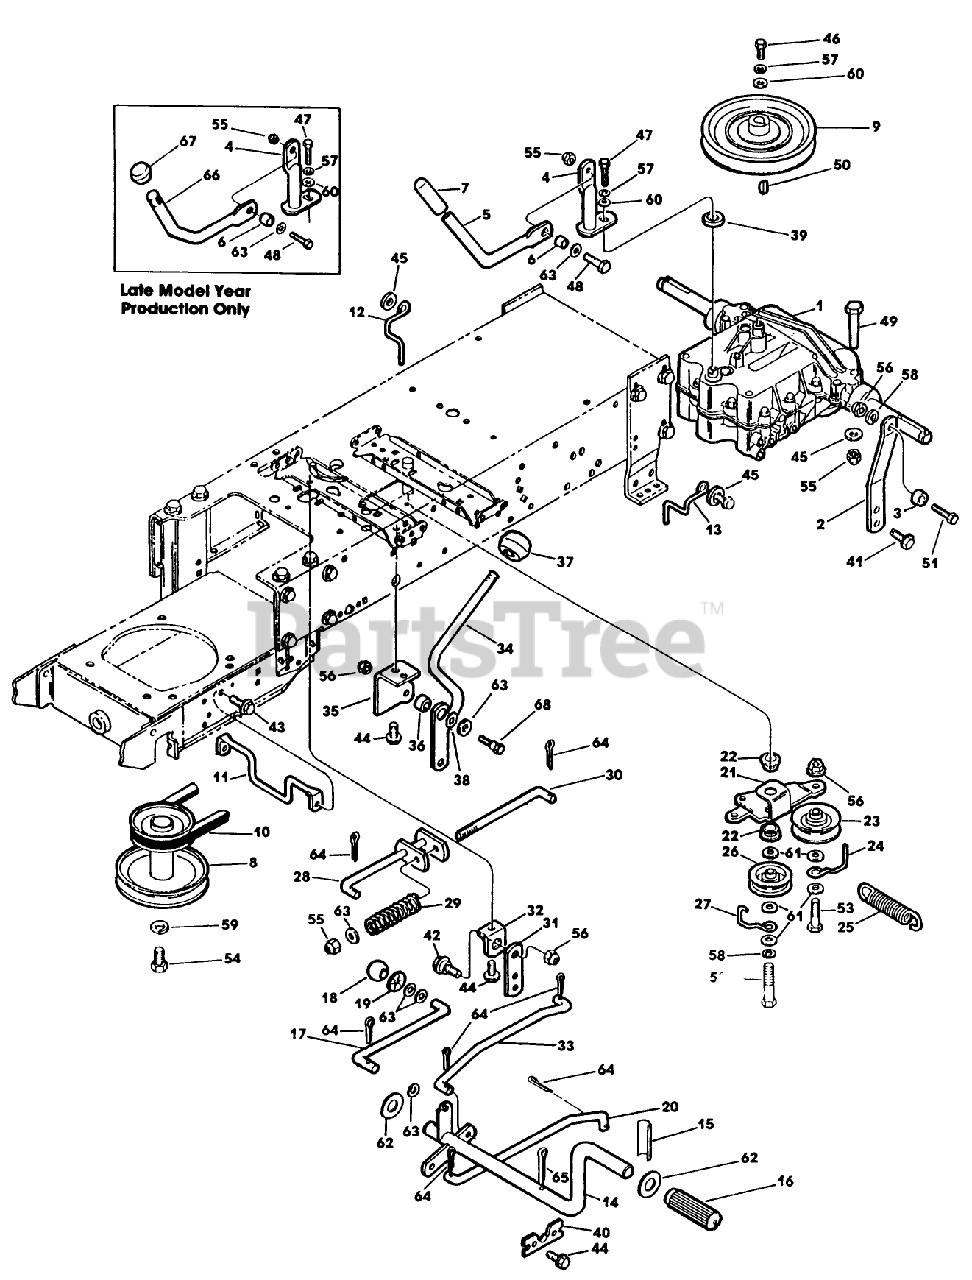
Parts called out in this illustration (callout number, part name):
4	LEVER AY-GEAR SEL.
8	PULLEY - ENGINE
9	PULLEY-TRANSMISSN
12	FINGER-BELT
13	FINGER-BELT
16	GRIP - FOOT PEDAL
23	PULLEY-IDLER "V"
27	RETAINER-BELT
31	LINK - BRAKE
47	SCREW-HEXHEAD
56	NUT-LOCKING
